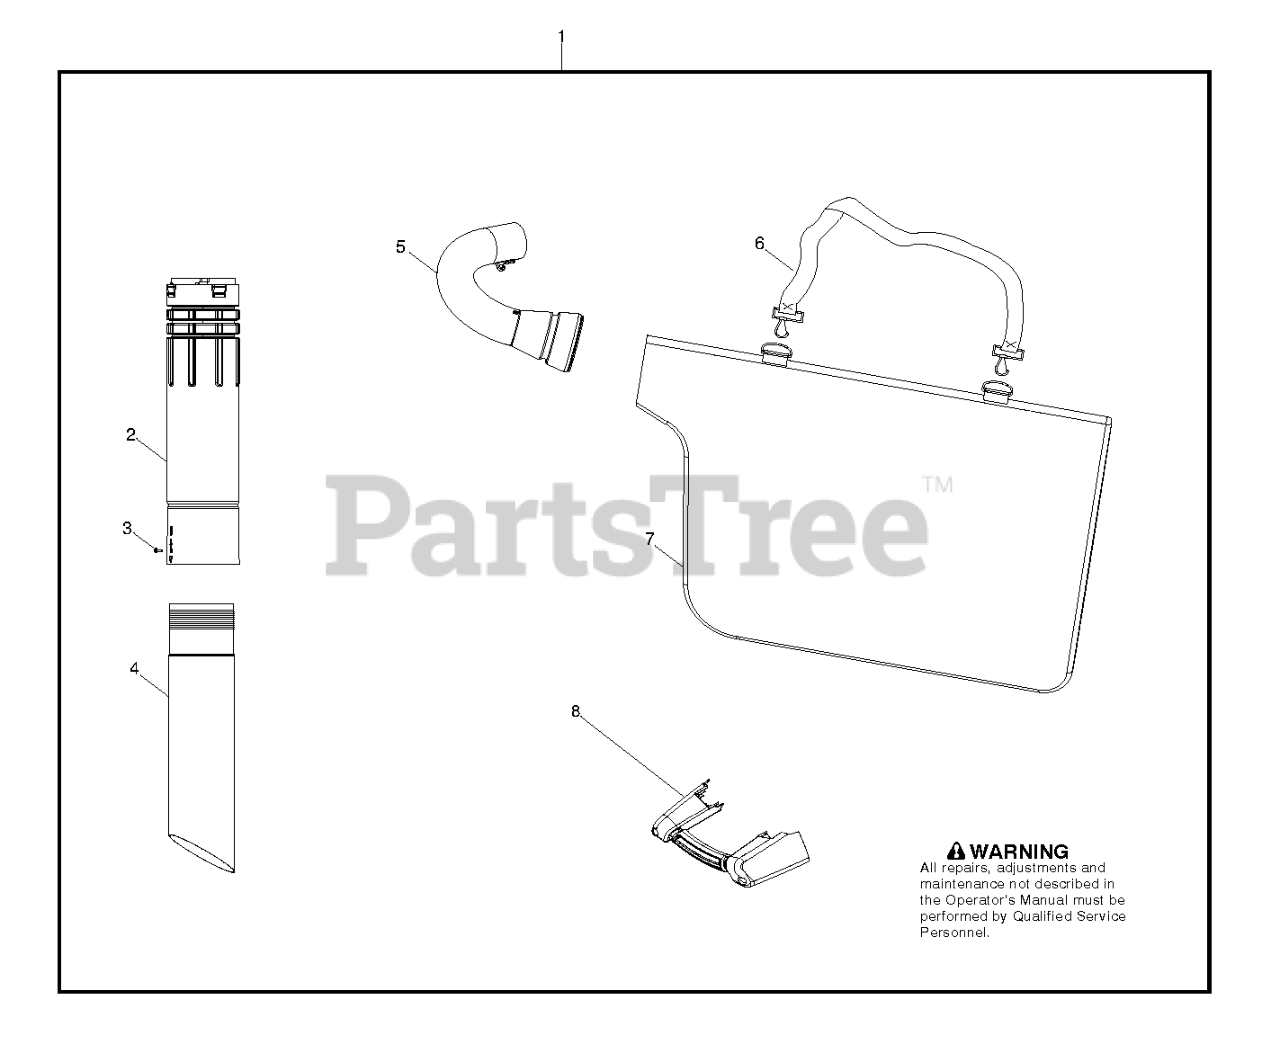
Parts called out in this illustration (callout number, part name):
2	ASSY - UPPER VAC TUBE
4	TUBE - LOWER VAC
5	TUBE ELBOW VACUUM BLACK
6	STRAP SHOULDER
7	VACUUM BAG
8	HANDLE - ASSIST
